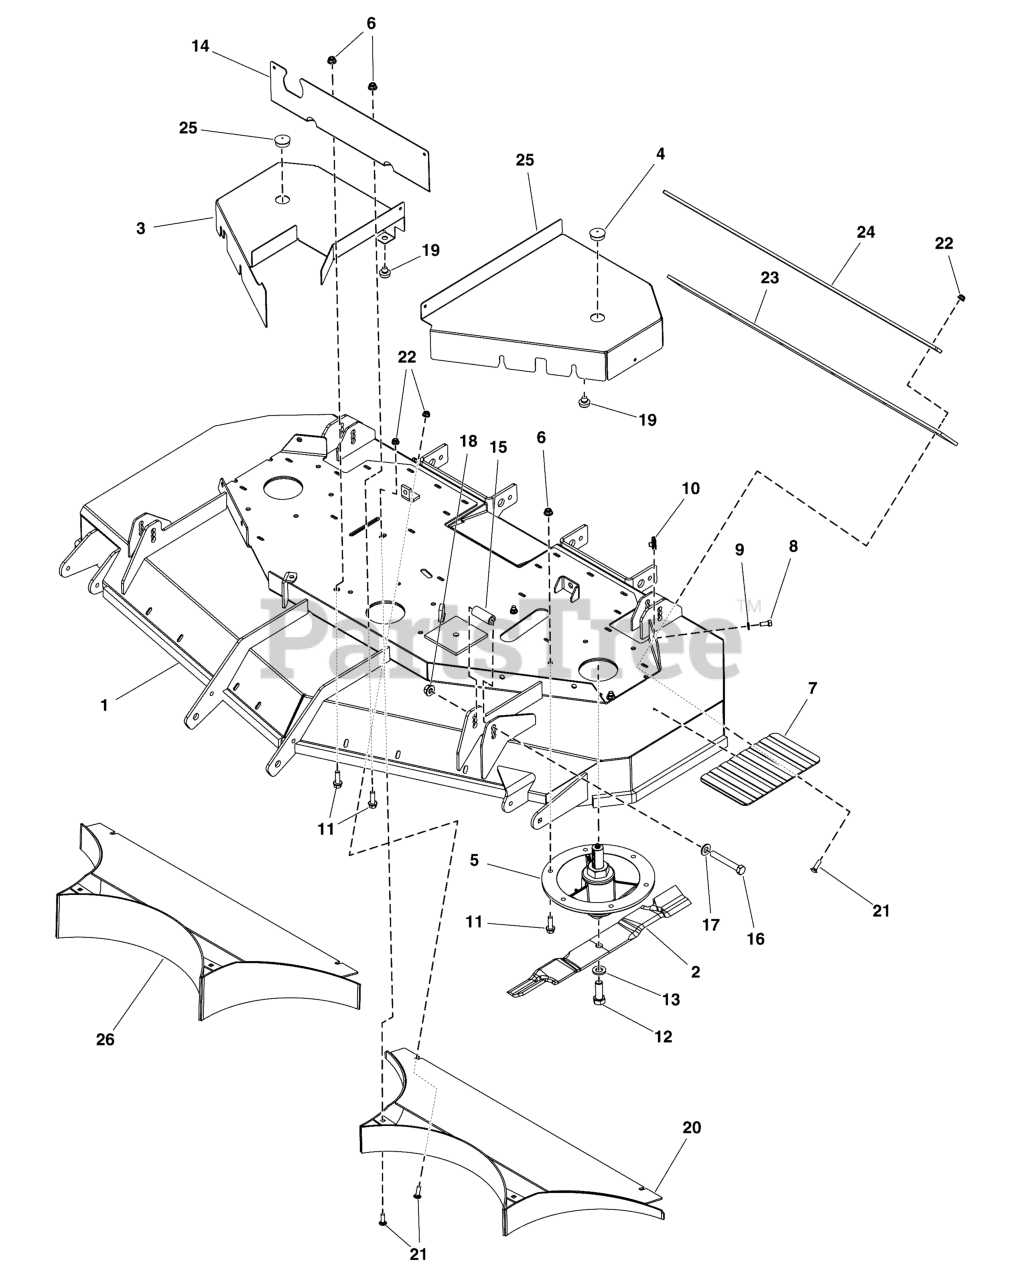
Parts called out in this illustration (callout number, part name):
1	DECK SHELL W/ DECALS, 3200, 61, RDCE
2	BLADE, SET, MULCH, 61 DECK
3	GUARD, RIGHT, 3200CE-RD-RED
4	GUARD, LEFT, 3200CE-RD-RED
5	SPINDLE ASSEMBLY
6	NUT, 3/8 - 16 HEX NYLOCK FLANGE
7	SAFETY WALK, 9.75 X 6.00
8	BOLT, 5/16-18 X 3/4 GD5
9	WASHER, 5/16" SAE
10	BODY CLIP, 5/16-18-7GA MATERIAL
11	BOLT, 3/8-16 X 1-1/4, FLANGE, GD 5, CZ
12	BOLT, 5/8-11 X 1-3/4 GD8
13	WASHER, BLADE BOLT, 9/16" F436, CZ
14	GUARD, FRONT, 3200CE-RD-RED
14	GUARD, FRONT, 3200-61RDCE - RED
15	SPACER, .52 X .88 X 2.16, CZ
16	BOLT, 1/2-13 X 3-1/2, HEX HD, GD5, CZ (SV)
17	WASHER, 1/2 SAE
18	NUT, Hex Flange, Nylock, 1/2-13
19	MNT, VBRTN, RBBR
20	WELD, REAR BAFFLE, 61CE-RD SHRT
21	BOLT, 5/16-18 X 1, CARRIAGE, GD5, CZ
22	NUT, 5/16-18 HEX NYLOCK FLANGE NUT
23	FLAP, STRIPPER, 3200-61RD
24	BAR, STRIPER CLAMP, 3200CE-61RD-BLK
25	PLUG, PANEL, 1.25 - BLACK
26	WELD, REAR BAFFLE, 61CE-RD TALL - BLK
